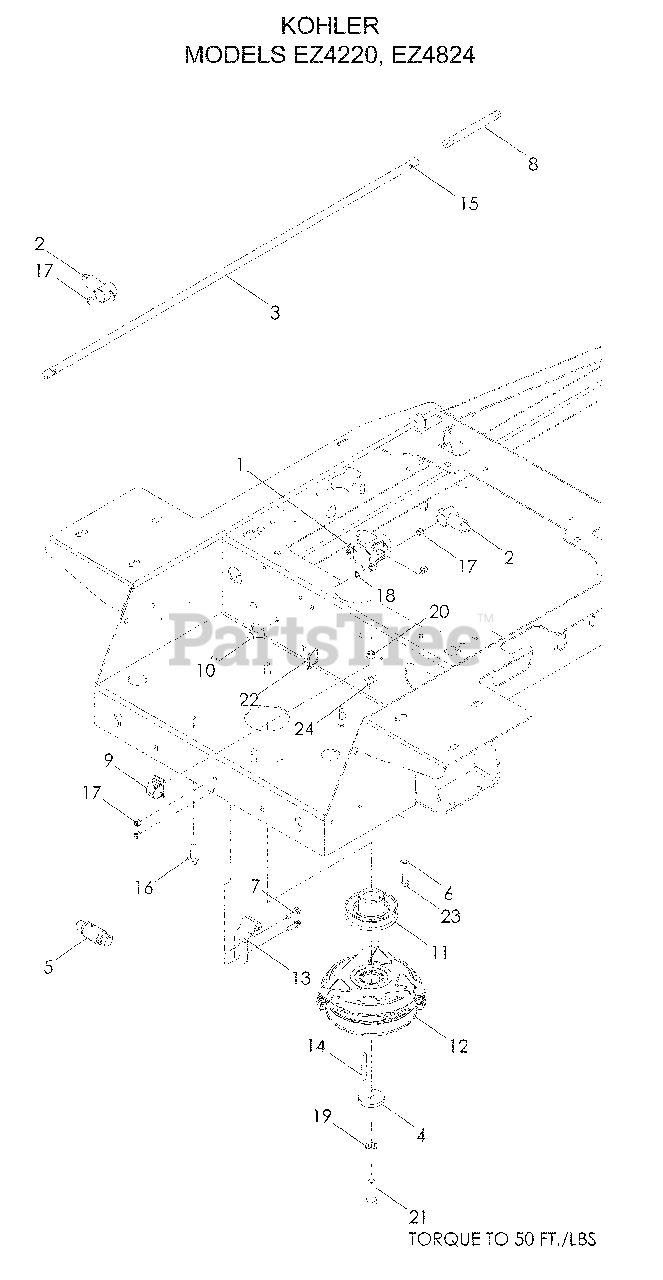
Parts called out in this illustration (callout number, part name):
2	INSULATOR, BATTERY
3	FUEL LINE, 35"
4	WASHER .469
5	PLUG OIL DRAIN
6	WASHER 5/16 EXT STAR
7	RHSNB ¼-20 x 1
8	FUEL LINE, 5"
9	PUSH-MOUNT WIRE CLIP
10	RHSSNB, ¼-20 x 5/8
11	PULLEY, DRIVE
13	CLUTCH TIE DOWN
14	KEY ¼ SQ x 2
15	CLAMP, HOSE
16	BOLT, 3/8-16 x 1 THD FORM
17	NUT ¼-20 NYLOC
19	WASHER 7/16
20	NUT 5/16-18 NYLOC
21	HCS 7/16-20 x 1½
23	HCS 5/16-18 x ¾
24	WASHER 5/16
